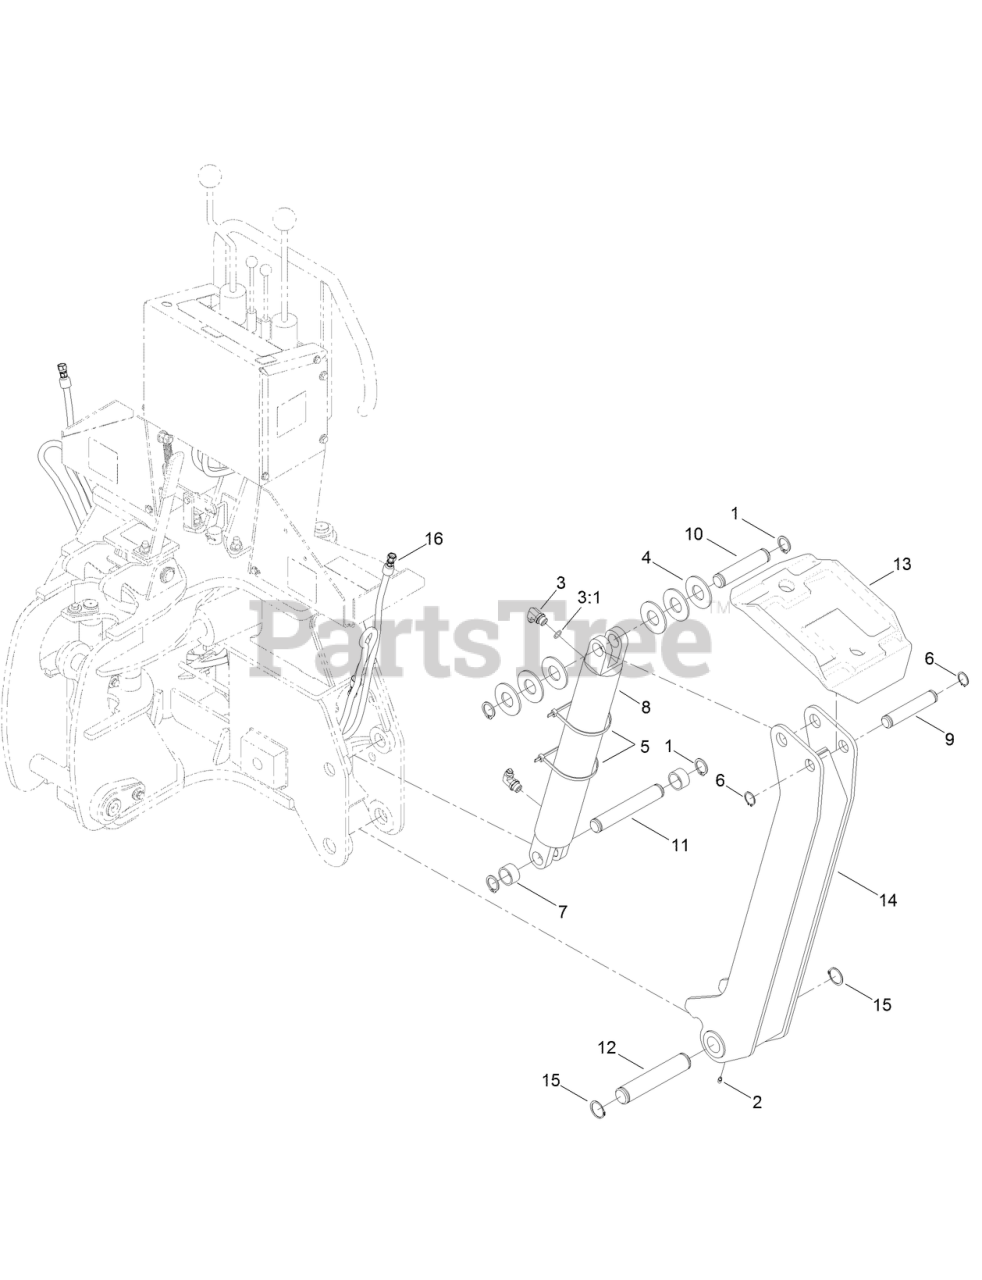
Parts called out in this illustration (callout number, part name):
1	RING-RETAINING, EXTERNAL
2	FITTING-GREASE
3	FITTING-ELBOW, 90 DEG
4	WASHER-FLAT (HARDENED)
5	TIE-CABLE
6	RING-RETAINING
7	BUSHING
8	HYD CYLINDER ASM
9	PIN (STABILIZER PAD END)
10	PIN-STABILIZER (CYLINDER ROD END)
11	PIN-STABILIZER CYLINDER TO ARM
12	PIN-Stabilizer Arm
13	PAD-STABILIZER
14	STABILIZER
16	HOSE ASM
